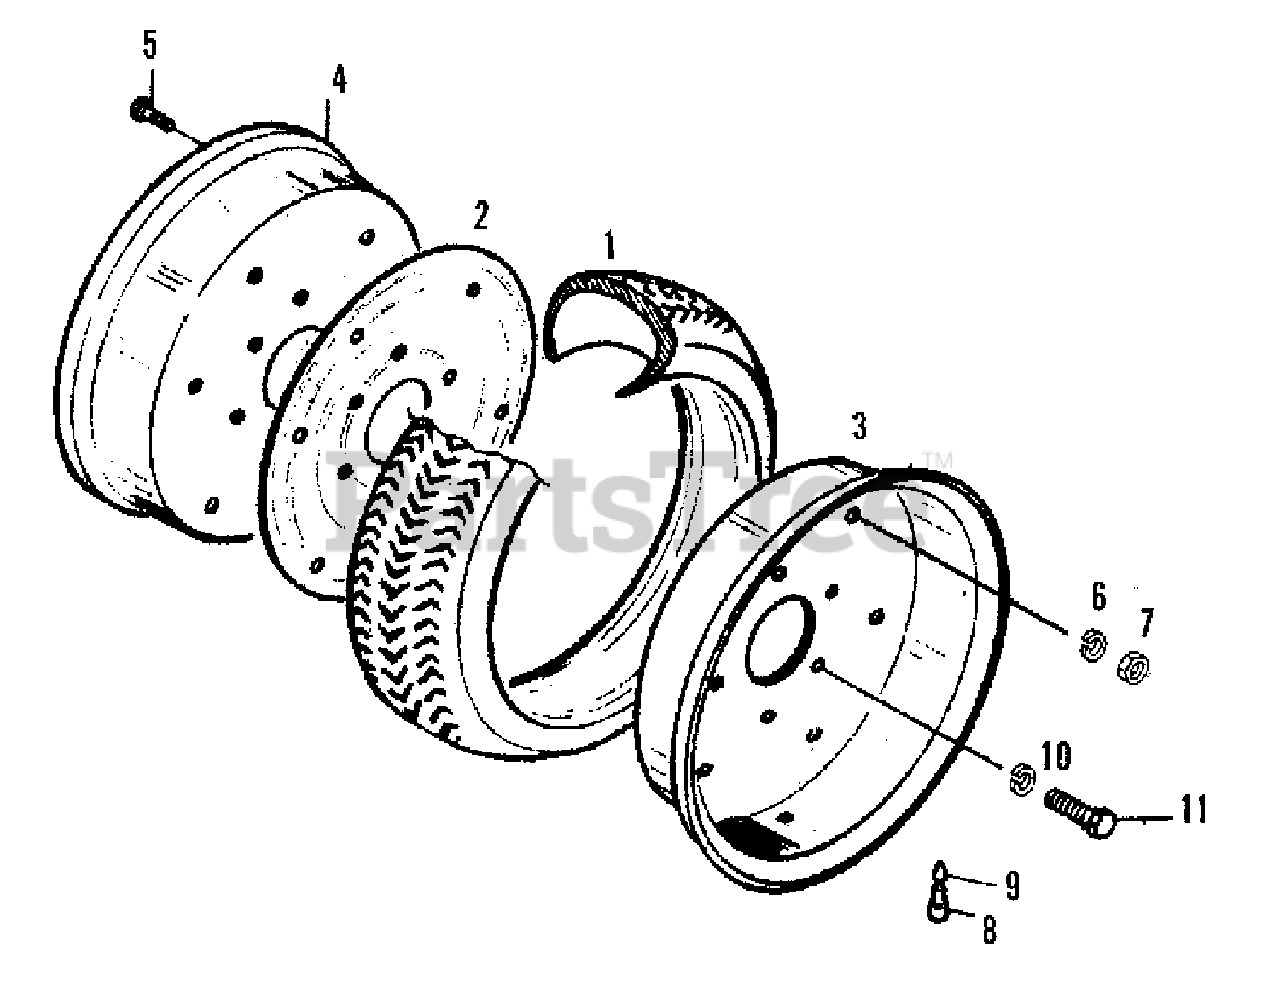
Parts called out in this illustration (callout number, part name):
1	TIRE (Obtain Locally)
2	GASKET, wheel
3	WHEEL (A)
4	WHEEL (B)
6	LOCKWASHER, M10
8	VALVE ASSEMBLY, (Obtain Locally)
9	CUP VALVE, (Obtain Locally
10	LOCKWASHER, M12
